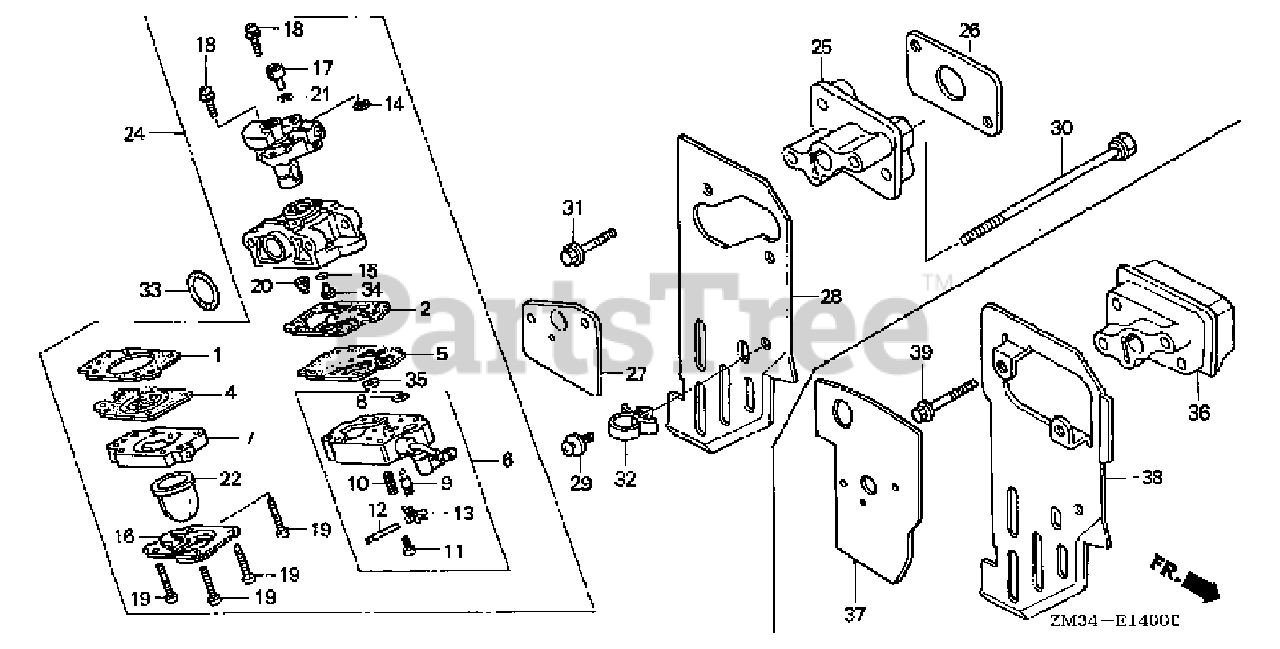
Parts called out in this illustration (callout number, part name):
1	GASKET, METERING DIAPHRAGM
2	GASKET, PUMP
4	DIAPHRAGM ASSY., METERING
5	DIAPHRAGM, PUMP
6	BODY ASSY., PUMP
7	BODY ASSY., AIR PURGE
8	SCREEN, INLET
9	VALVE, IN. NEEDLE
10	SPRING, METERING LEVER
11	SCREW, METERING LEVER PIN
12	PIN, METERING LEVER
13	LEVER, METERING
14	RING, SPRING RETAINING
15	O-RING
16	COVER, PRIMER PUMP
17	SWIVEL
18	SCREW, THROTTLE COLLAR
19	SCREW, PUMP COVER
20	SPRING, PUMP
21	WASHER
22	PUMP, PRIMER
24	CARBURETOR ASSY. (WYL-68A)
24	CARBURETOR ASSY. (WYL-97)
24	CARBURETOR ASSY. (WYL-127)
25	INSULATOR, CARBURETOR
26	GASKET, INSULATOR
27	GASKET, CARBURETOR
28	GUIDE, AIR IN.
29	SCREW-WASHER (5X10)
30	BOLT, HEX. (5X75)
31	BOLT, FLANGE (5X22)
32	CLIP, WIRE HARNESS
33	O-RING (14.8X2.4)
34	JET (#33.5)
34	JET (#34)
34	JET (#35)
34	JET (#38)
34	JET (#39)
34	JET (#40)
34	JET (#41)
34	JET (#42)
34	JET (#43)
35	FILTER, FUEL INLET
36	INSULATOR, CARBURETOR
37	GASKET, CARBURETOR
38	GUIDE, AIR IN.
39	BOLT, FLANGE (5X32)
